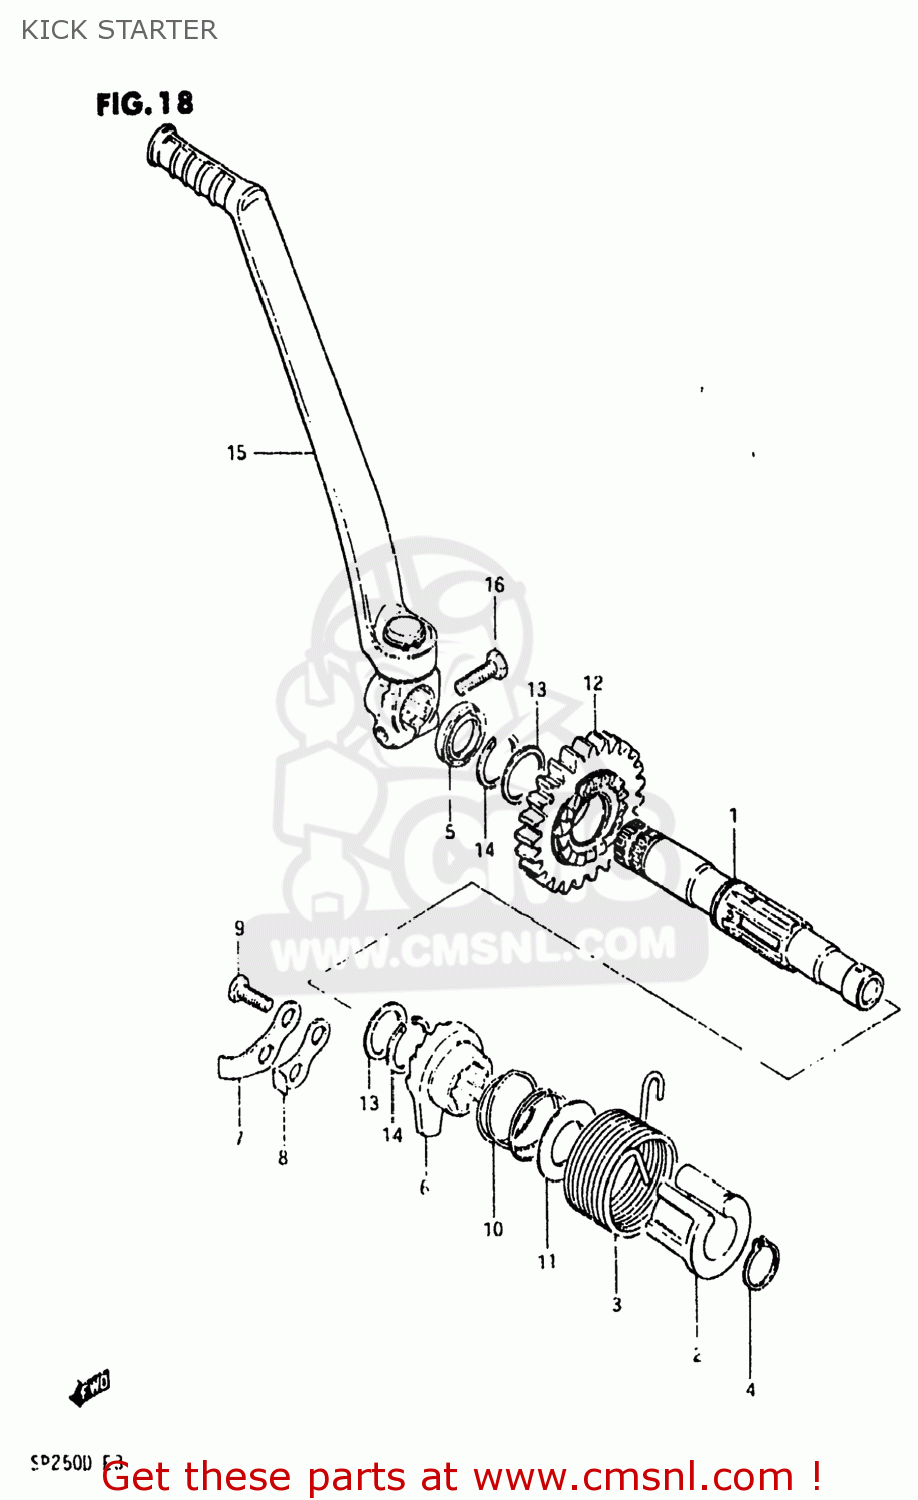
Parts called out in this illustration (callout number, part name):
1	SHAFT,KICK STARTER
2	GUIDE,KICK STARTER SFT SPRING
3	SPRING
4	CIRCLIP
5	SEAL,OIL(20X27X5)
6	STARTER,KICK
7	GUIDE,KICK STARTER
8	STOPPER,KICK STARTER
9	BOLT
10	SPRING
11	WASHER
12	GEAR,KICK STARTER DRIIVE
13	SHIM
14	CIRCLIP
15	LEVER ASSEMBLY,KICK STARTER
16	BOLT 8X25
